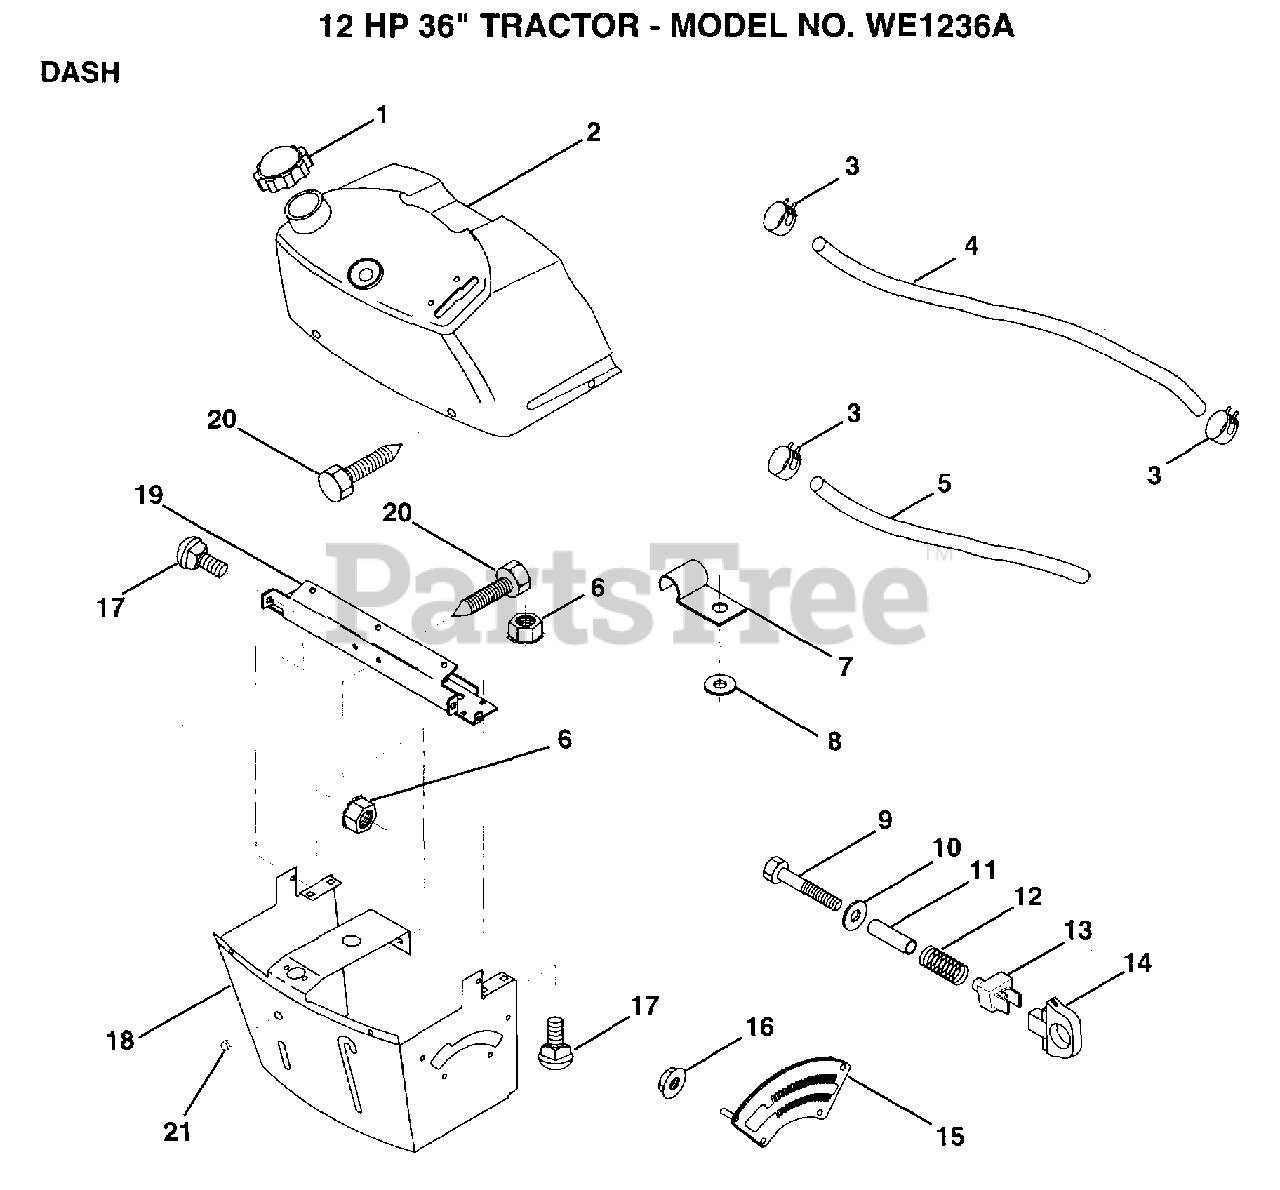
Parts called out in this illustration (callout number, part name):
1	CAP BLK FUEL LR
2	TANK.ASM.DASH.LR
3	HOSE CLAMP
5	FUEL LINE T
6	NUT
7	CLIP T
8	WASHER PM
9	BOLT
11	SPACER SPLIT
12	SPRING M
13	"KNOB,HGT RETAINER"
14	KNOB
15	ADJUSTER QUAD
16	NUT
17	BOLT
18	SUPT ASSY DASH
19	CROSS BRACE
20	SCREW.1/4-20X1/2
21	PLUG DOME
